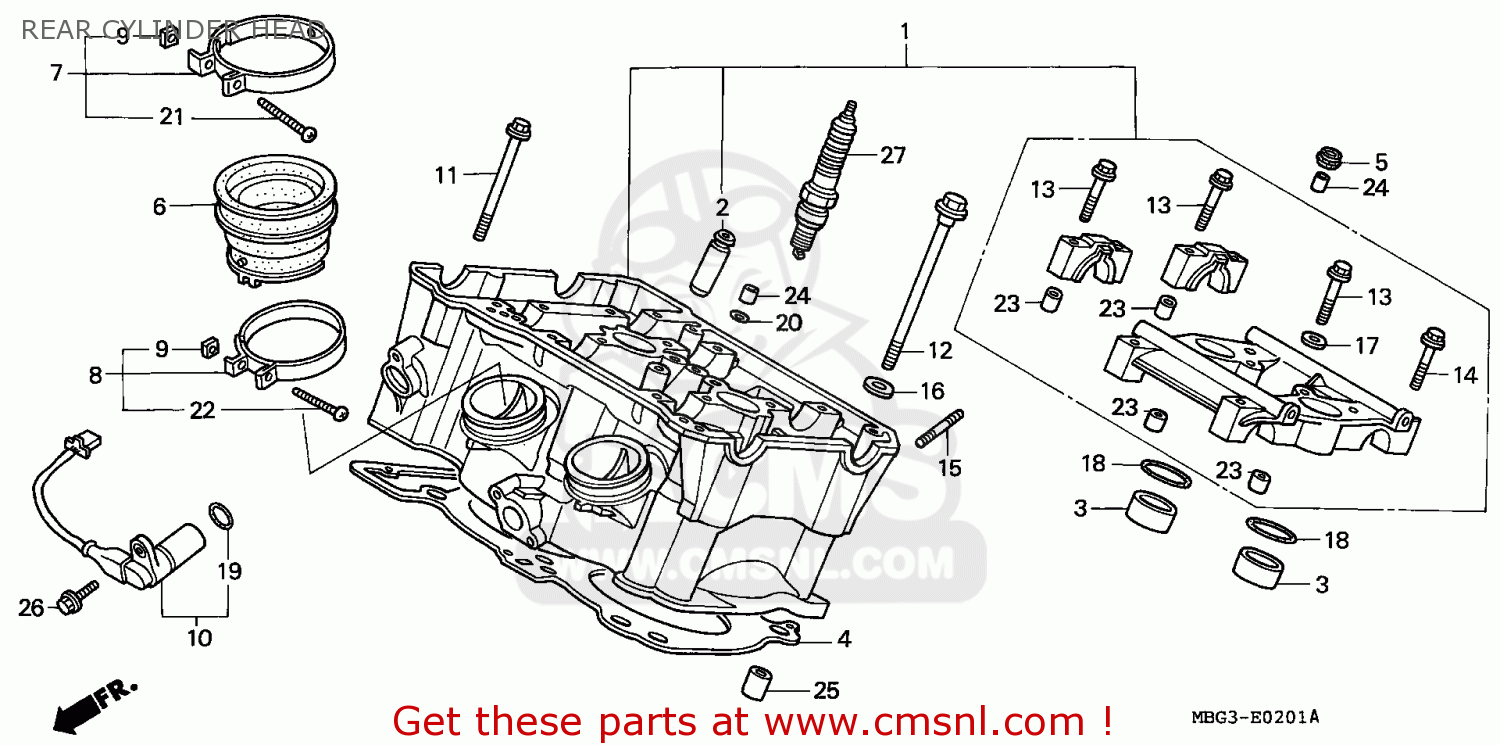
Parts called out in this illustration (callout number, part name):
1	HEAD ASSY,REAR
2	GUIDE,VALVE OSZ
3	COLLAR,25MM
4	GASKET,REAR HEAD (NAS)
5	GASKET C,HEAD COV (NAS)
6	INSULATOR,THROT B
7	BAND,INSULATOR
8	BAND B,INSULATOR
9	NUT,SQUARE,5MM
10	PULSER ASSY,CAM .
11	BOLT,FLANGE 6X77
12	BOLT,FLANGE,9X98
13	BOLT,FLANGE 6X48
14	BOLT,FLG.,6X39.5
15	BOLT STUD,6X22
16	WASHER,9MM
17	WASHER,SEALING,6.
18	O RING,24.5X1.9
19	O-RING 16X2.1
20	O-RING, 9.8X1.9
21	SCREW,PAN,5X25
22	SCREW,CROSS 5X28
25	DOWEL,PIN,12X20
26	BOLT FLANGE 6X18
27	PLUG,SPARK(CR9EH9
